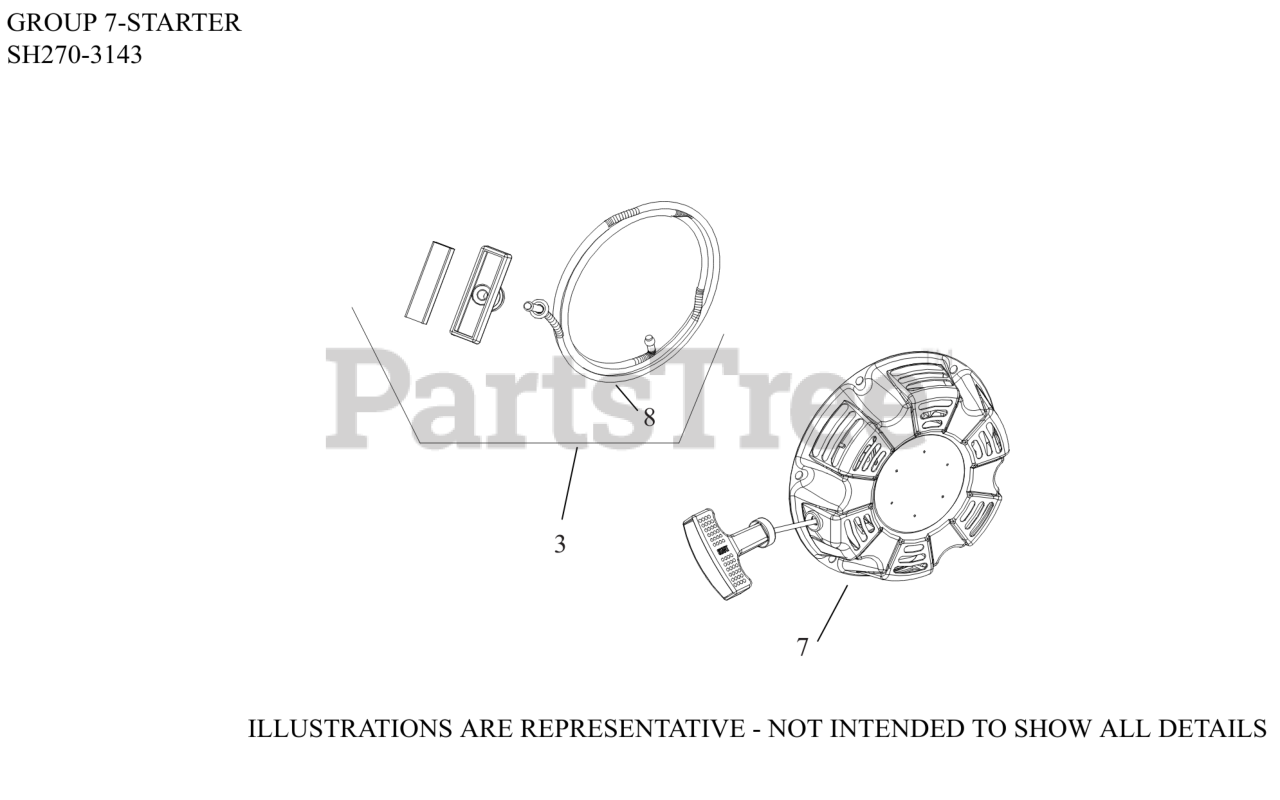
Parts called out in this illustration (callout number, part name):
3	KIT, STARTER ROPE W/HANDLE
7	RETRACTABLE STARTER ASSEMBLY
8	ROPE, STARTING
